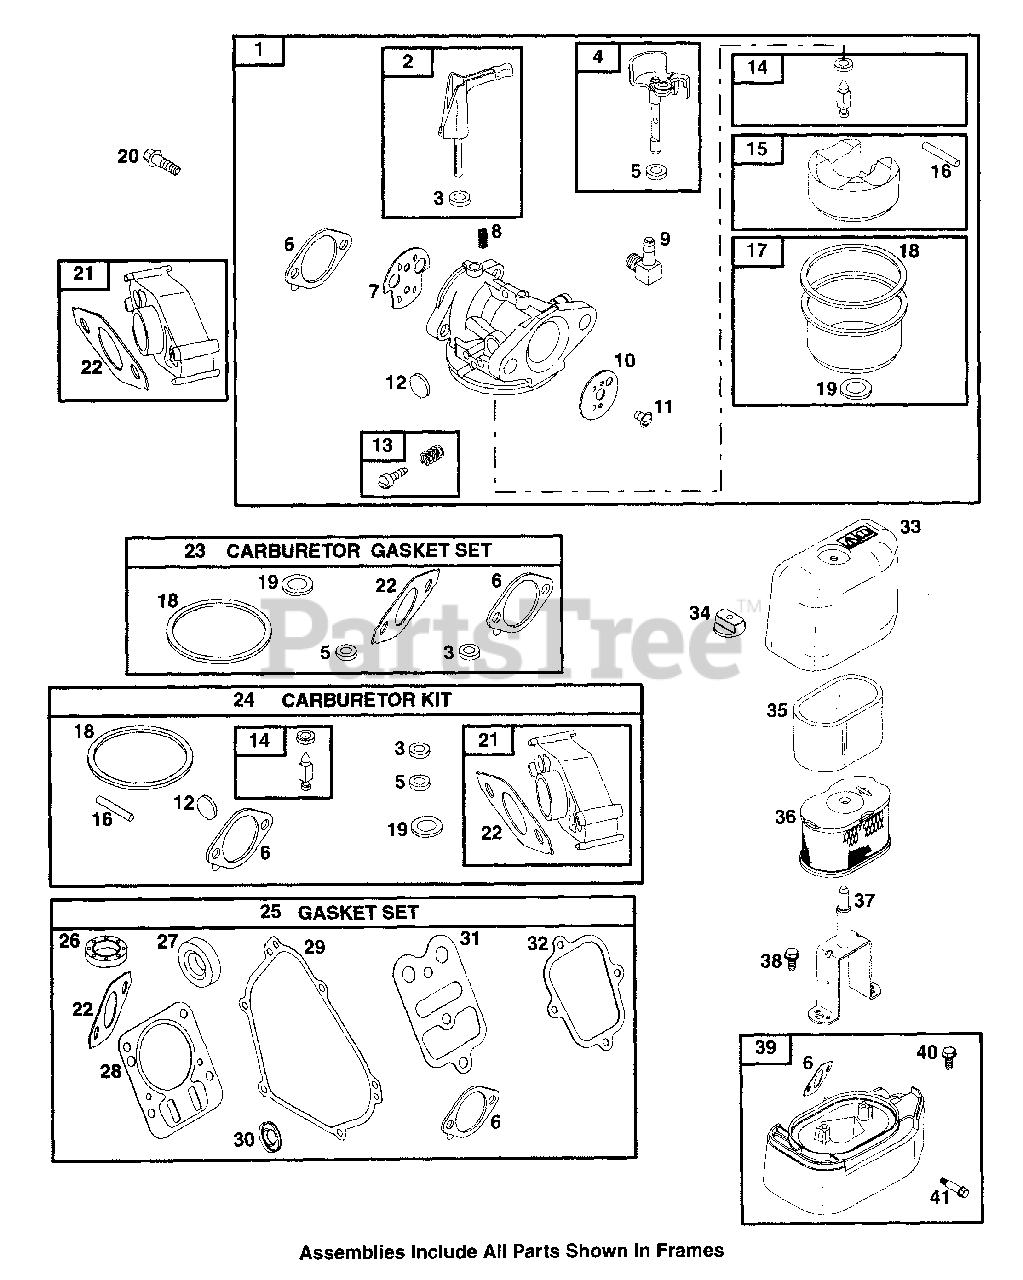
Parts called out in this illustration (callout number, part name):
1	Carburetor
2	Shaft-Choke
3	Washer (Choke Shaft Seal)
4	Shaft-Throttle
5	Washer (Throttle Shaft)
6	Gasket-Air Cleaner
7	Valve-Choke
8	Spring-Detent (Choke)
9	Connector-Hose
10	Valve-Throttle
11	Screw (Throttle Valve)
12	Plug-Welch
13	Kit-Idle Speed
14	Valve-Needle
15	Float-Carburetor
16	Pin-Float Hinge
17	Bowl-Float
18	Gasket-Float Bowl
19	Washer-Seal
20	Screw (Carburetor)
21	Spacer-Carburetor
22	Gasket-Intake
23	Gasket Set-Carburetor
24	Carburetor Kit
25	Gasket Set
26	Seal-Oil
28	Cylinder Head Gasket
29	Gasket-Crankcase
30	Seal-Valve
31	Gasket-Plate
32	Gasket-Rocker Cover
33	Cover-Air Cleaner
34	Knob-Air Cleaner
35	Filter-Air (Pre-Filter)
36	Filter A/C Cartridge
37	Air Cleaner Bracket
38	Screw (Air Cleaner Bracket)
39	Base-Air Cleaner
40	Screw (Air Cleaner Base)
41	Screw (Air Cleaner Base)
